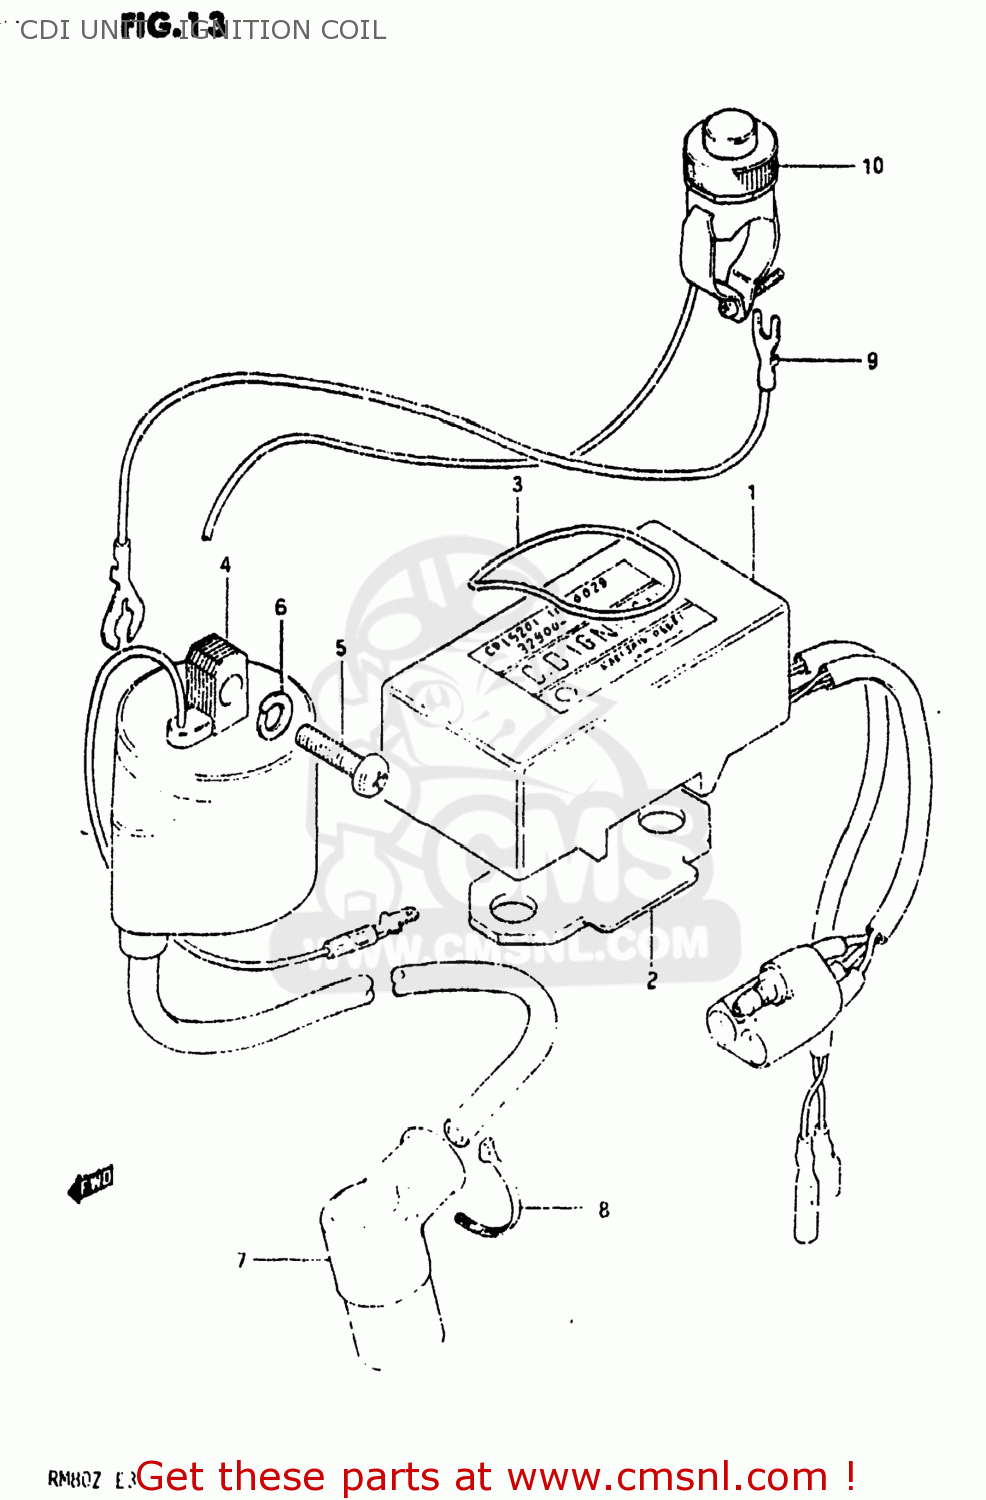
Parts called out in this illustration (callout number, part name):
1	CDI UNIT
2	PROTECTOR,CDI UNIT
3	O-RING
4	COIL ASSEMBLY,IGNITION
5	SCREW
6	LOCK WASHER
7	CAP,SPARK PLUG
8	CLAMP
9	WIRE,ENGINE STOP EARTH
10	SWITCH ASSEMBLY
